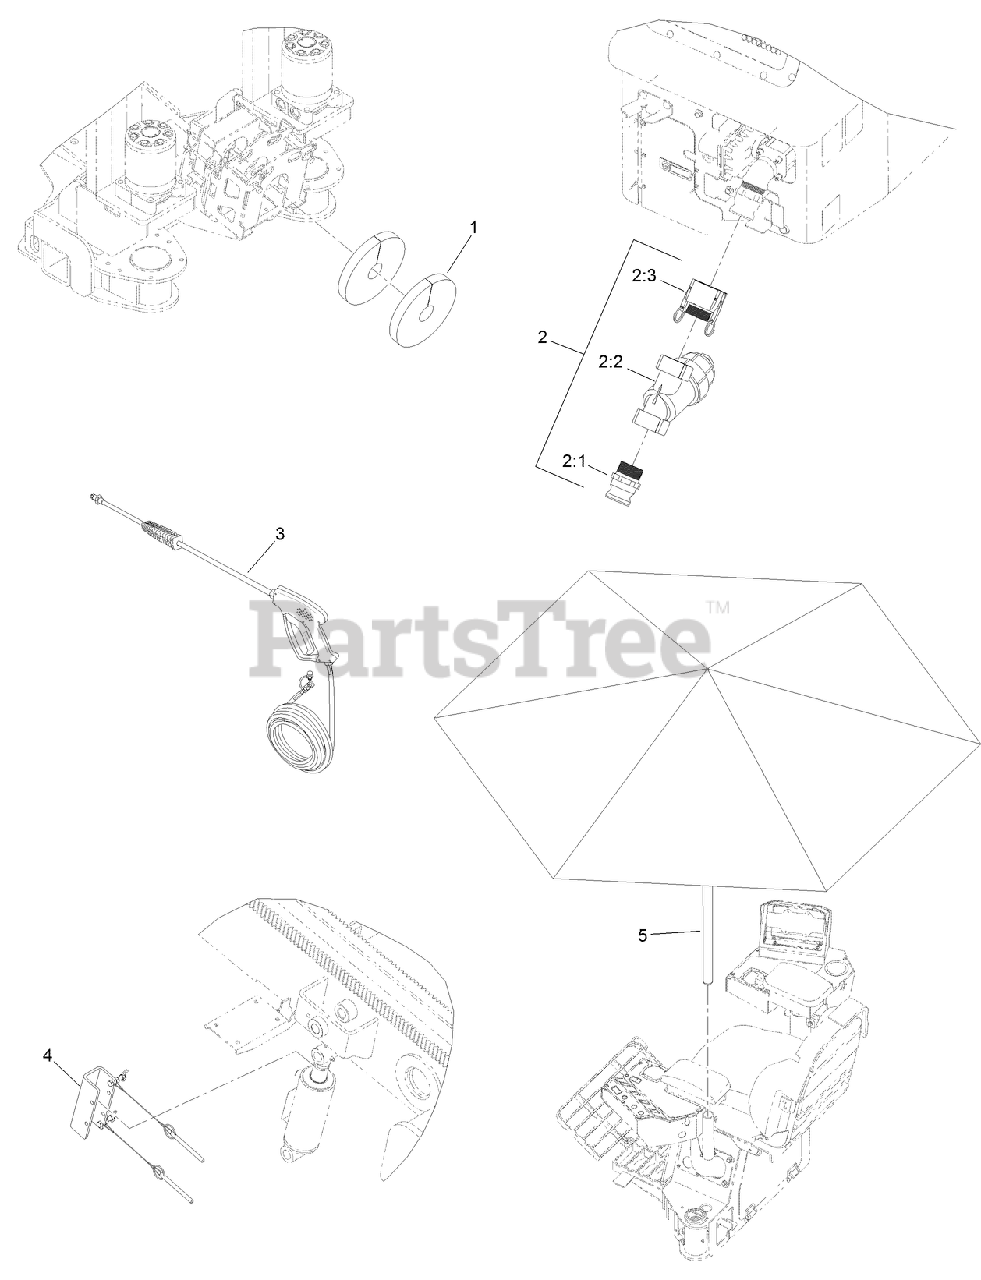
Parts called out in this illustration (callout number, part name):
1	WIPER-PIPE
2	STRAINER KIT
2:1	ADAPTER-MALE
2:2	STRAINER-Y
2:3	FITTING-CAMLOK
3	WASH DOWN WAND ASM
4	CYLINDER LOCKOUT ASM
5	UMBRELLA-TORO
